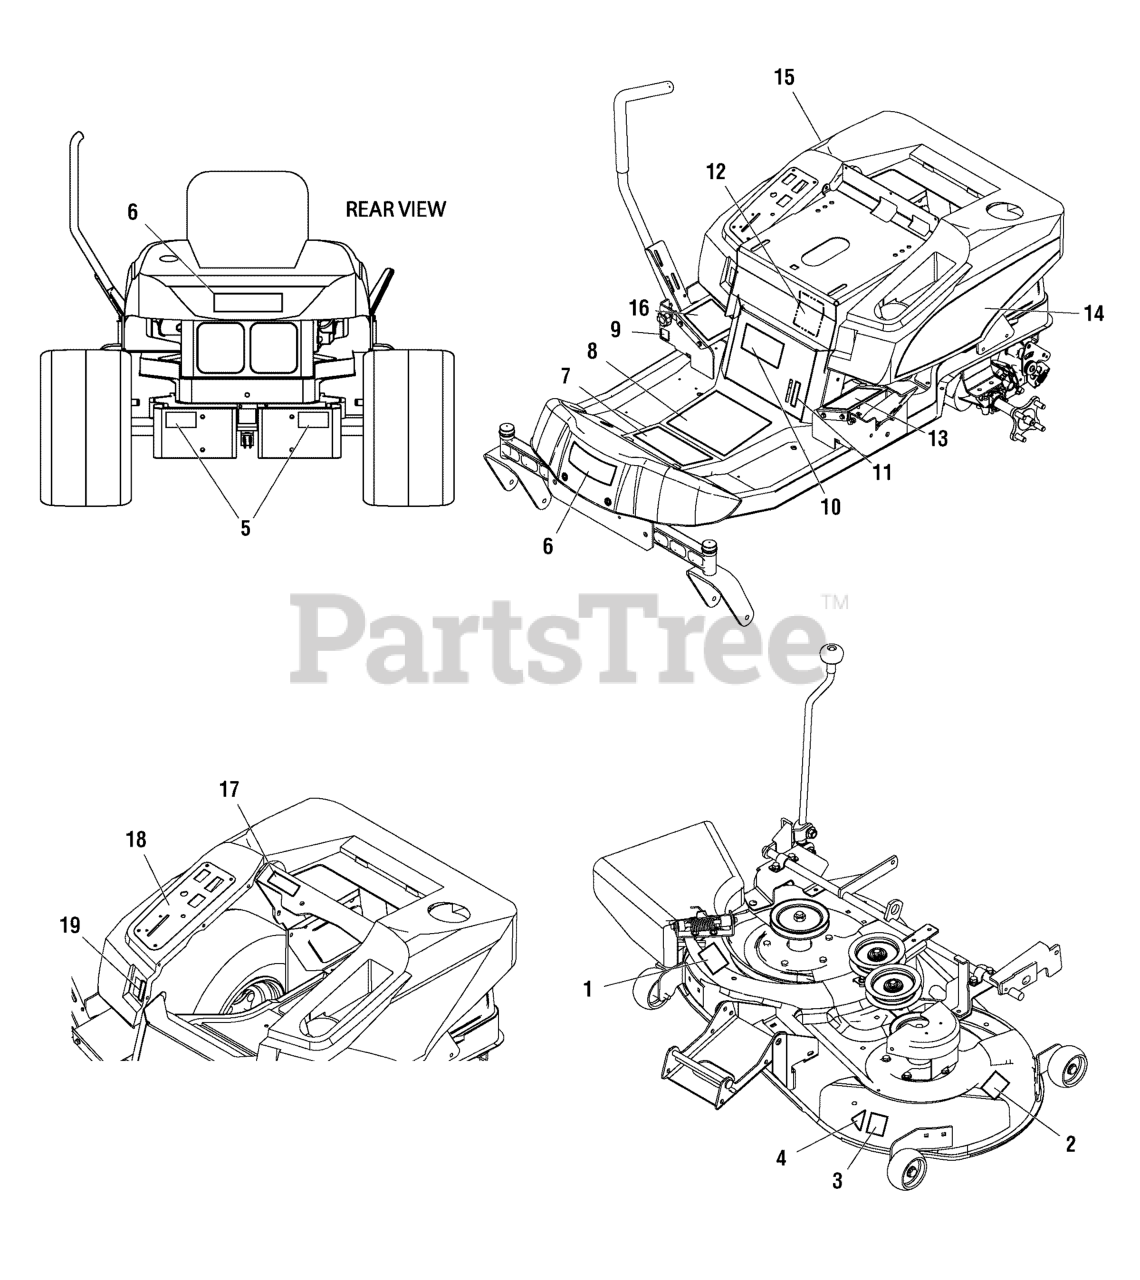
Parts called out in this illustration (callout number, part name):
1	DECAL, Danger Do No Operate without Deflector
2	DECAL, Danger Do Not Put Hands/Feet in Mower
3	DECAL, 42" 2006 Silver/Black
4	DECAL, OPEI Certified ANSI B71.12003 Gold
5	DECAL, Transmission Release Instructions
6	DECAL, Craftsman ZTS
7	DECAL, Operator Instructions Front
8	DECAL, Operator Intructions Bottom
9	DECAL, Tracking Adjustment ZT 7000
10	DECAL, ZTS 7500, 20/42
11	DECAL, Height of Cut
12	DECAL, Service Parts Attachments ZT 20/42
13	DECAL, Handle Control L.H. ZTS 7500
14	DECAL, Seat Deck L.H. Craftsman ZTS
15	DECAL, Seat Deck R.H. Craftsman ZTS
16	DECAL, Handle Control R.H. ZTS 7500
17	DECAL, Do Not Remove Foam Around Engine
18	DECAL, Instrument Panel ZTS 7500
19	DECAL, Height of Cut
